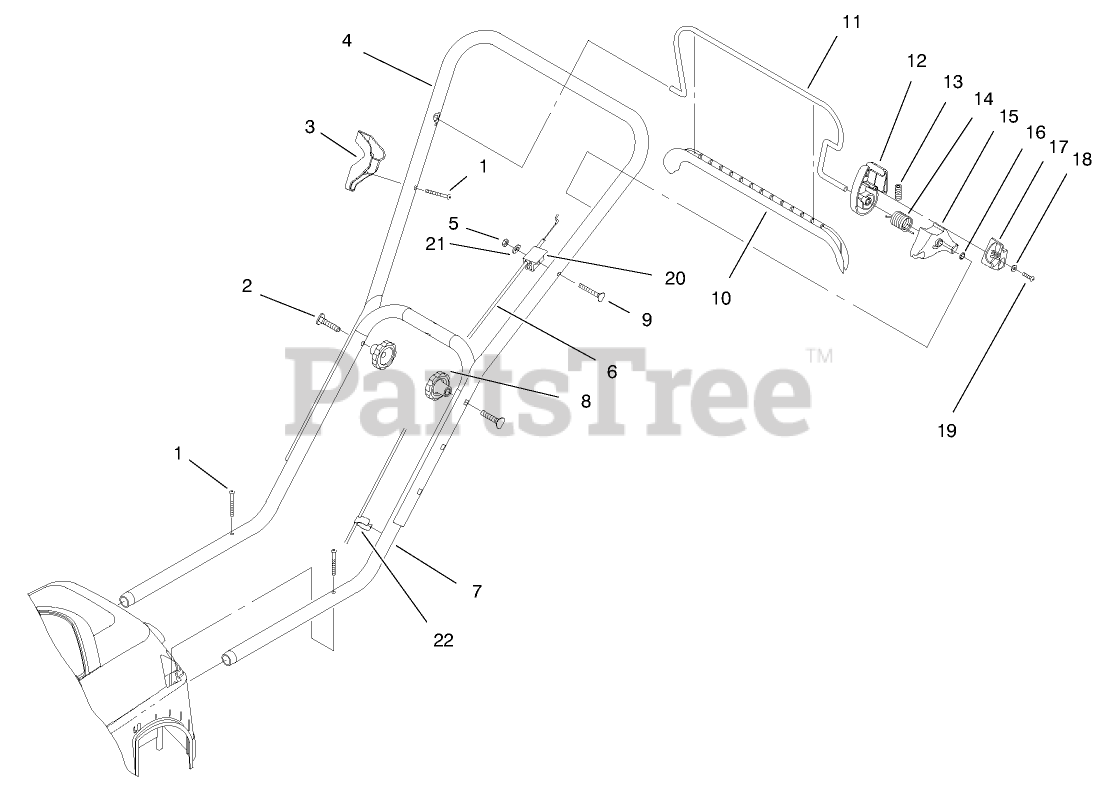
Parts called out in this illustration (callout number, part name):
1	SCREW-PPH
2	SCREW-HANDLE
3	LOCK - CORD
5	NUT-HEX
6	CABLE - CONTROL
9	SCREW-HANDLE
12	HOUSING - BAIL
13	SPRING - COMPRESSION
14	SPRING - BAIL
16	NUT - PUSH
17	SLIDE
18	WASHER - FLAT
19	SCREW-PPH
21	WASHER-FLAT
